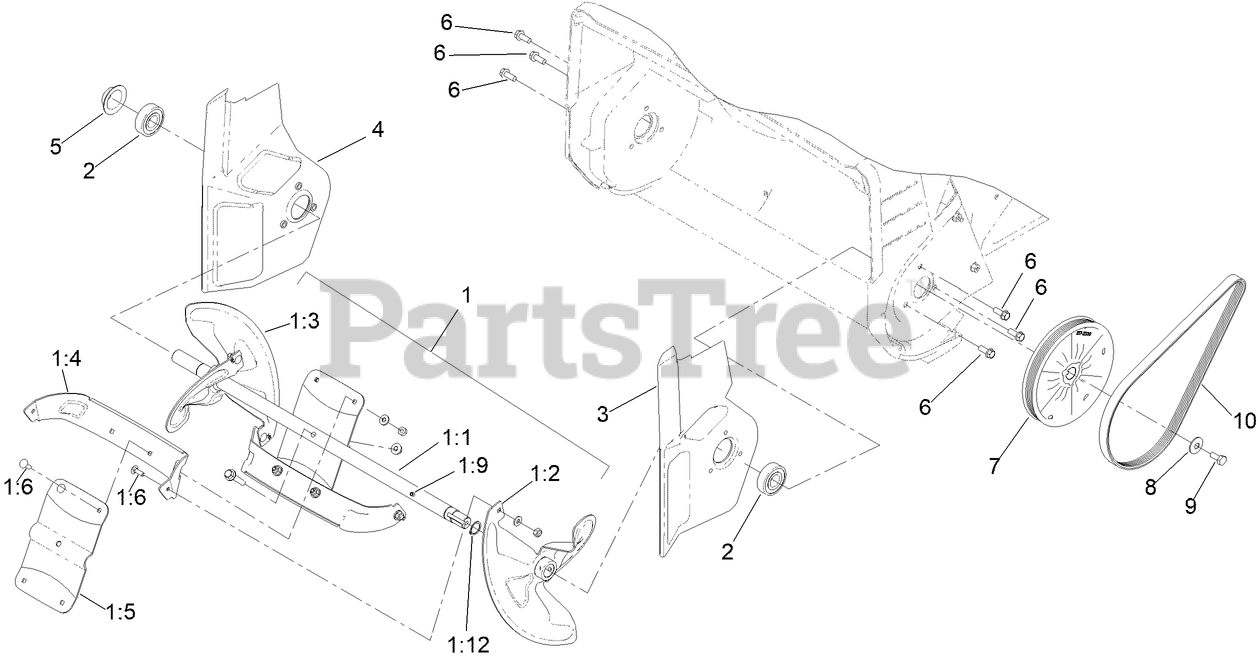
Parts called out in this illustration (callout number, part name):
1	ROTOR ASM
1:1	SHAFT-ROTOR
1:2	BLADE-ROTOR, LH
1:3	BLADE-ROTOR, RH
1:4	ROTOR-CENTER
1:5	PADDLE-CENTER
1:6	SCREW-CARR
1:9	PIN-SPIRAL
1:12	RING-SNAP, EXTERNAL
2	BEARING-BALL
3	EXTENSION-LH
4	EXTENSION-RH
5	CAP-SIDEPLATE, RH
6	SCREW-HWH
7	ROTOR PULLEY ASM (6 GROOVE)
8	WASHER-BELLEVILLE
9	SCREW-HH LOCK
10	BELT-V, RIBBED
